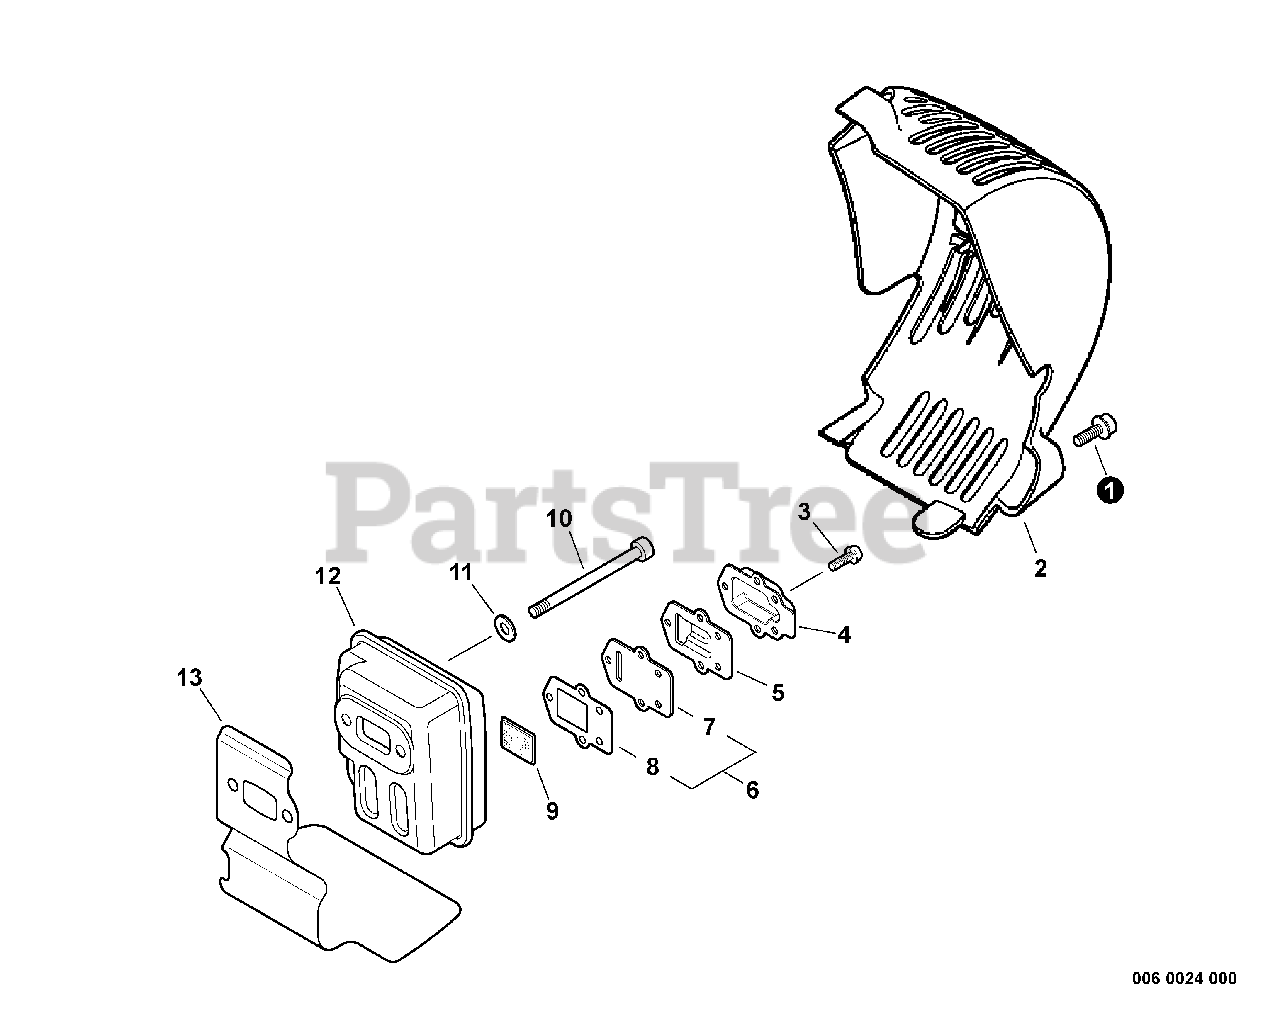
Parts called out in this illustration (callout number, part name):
1	BOLT 5×14
2	COVER, MUFFLER
3	SCREW 4×10
4	GUIDE, EXHAUST
5	GUIDE, EXHAUST
6	GASKET KIT, EXHAUST
7	GUIDE, EXHAUST
8	GASKET, EXHAUST
9	SCREEN, SPARK ARRESTER
11	WASHER 5.5×12×0.8
12	MUFFLER
13	HEAT SHIELD, EXHAUST
